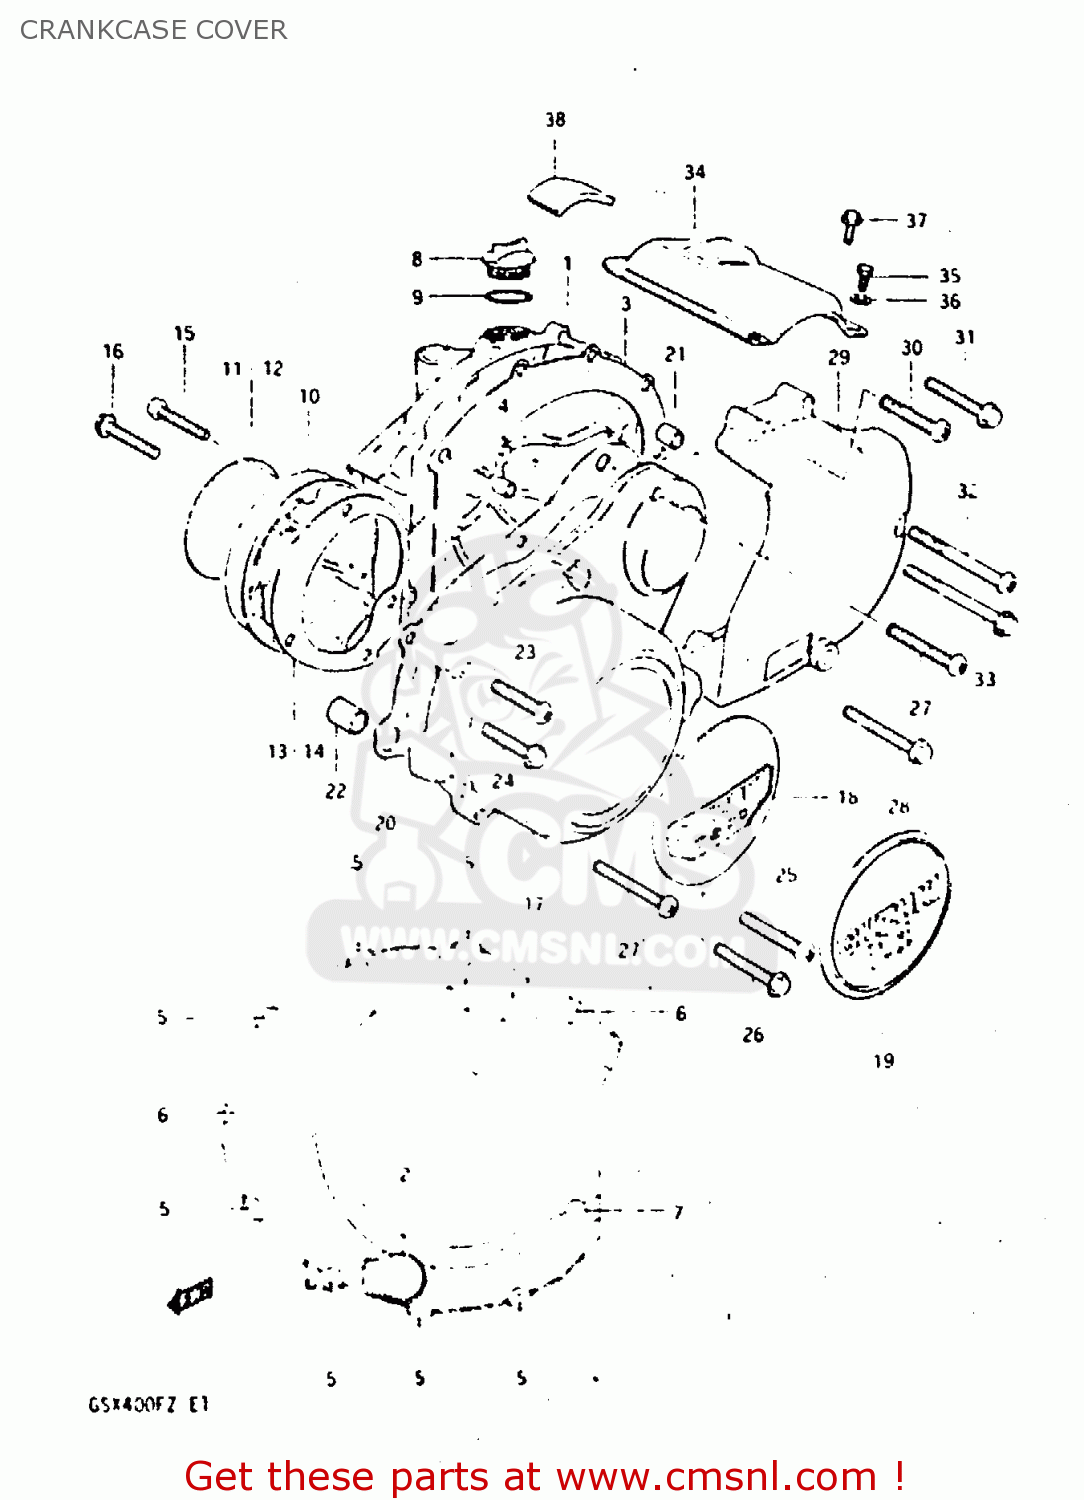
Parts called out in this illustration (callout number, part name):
1	COVER, CLUTCH
2	LENS, OIL LEVEL
3	GASKET (MCA)
4	PIN
5	BOLT
6	SCREW 6X30
7	BOLT
8	PLUG
9	O-RING
10	COVER, CONTACT BREAKER
11	EMBLEM,CONTACT
12	EMBLEM,CONTACT BREAKER COVER
13	GASKET,CONTACT BREAKER COVER (MCA)
14	GASKET,CONTACT BREAKER COVER (NAS)
15	SCREW
16	BOLT (5*30)
17	COVER,MAGNETO
18	EMBLEM,MAGNETO COVER
19	EMBLEM,MAGNETO COVER
20	GASKET (MCA)
21	PIN
22	PIN
23	SCREW 6X30
24	BOLT (6X30)
25	SCREW (6X35)
26	BOLT (6X35)
27	SCREW
28	BOLT (6X40)
29	COVER, ENGINE SPROCKET
30	SCREW (6X35)
31	BOLT (6X35)
32	SCREW 6X65
33	BOLT (6X65)
34	COVER
35	BOLT 5X16
36	WASHER
37	BOLT (5*8)
38	DAMPER,STARTER MOTOR CLUTCH
